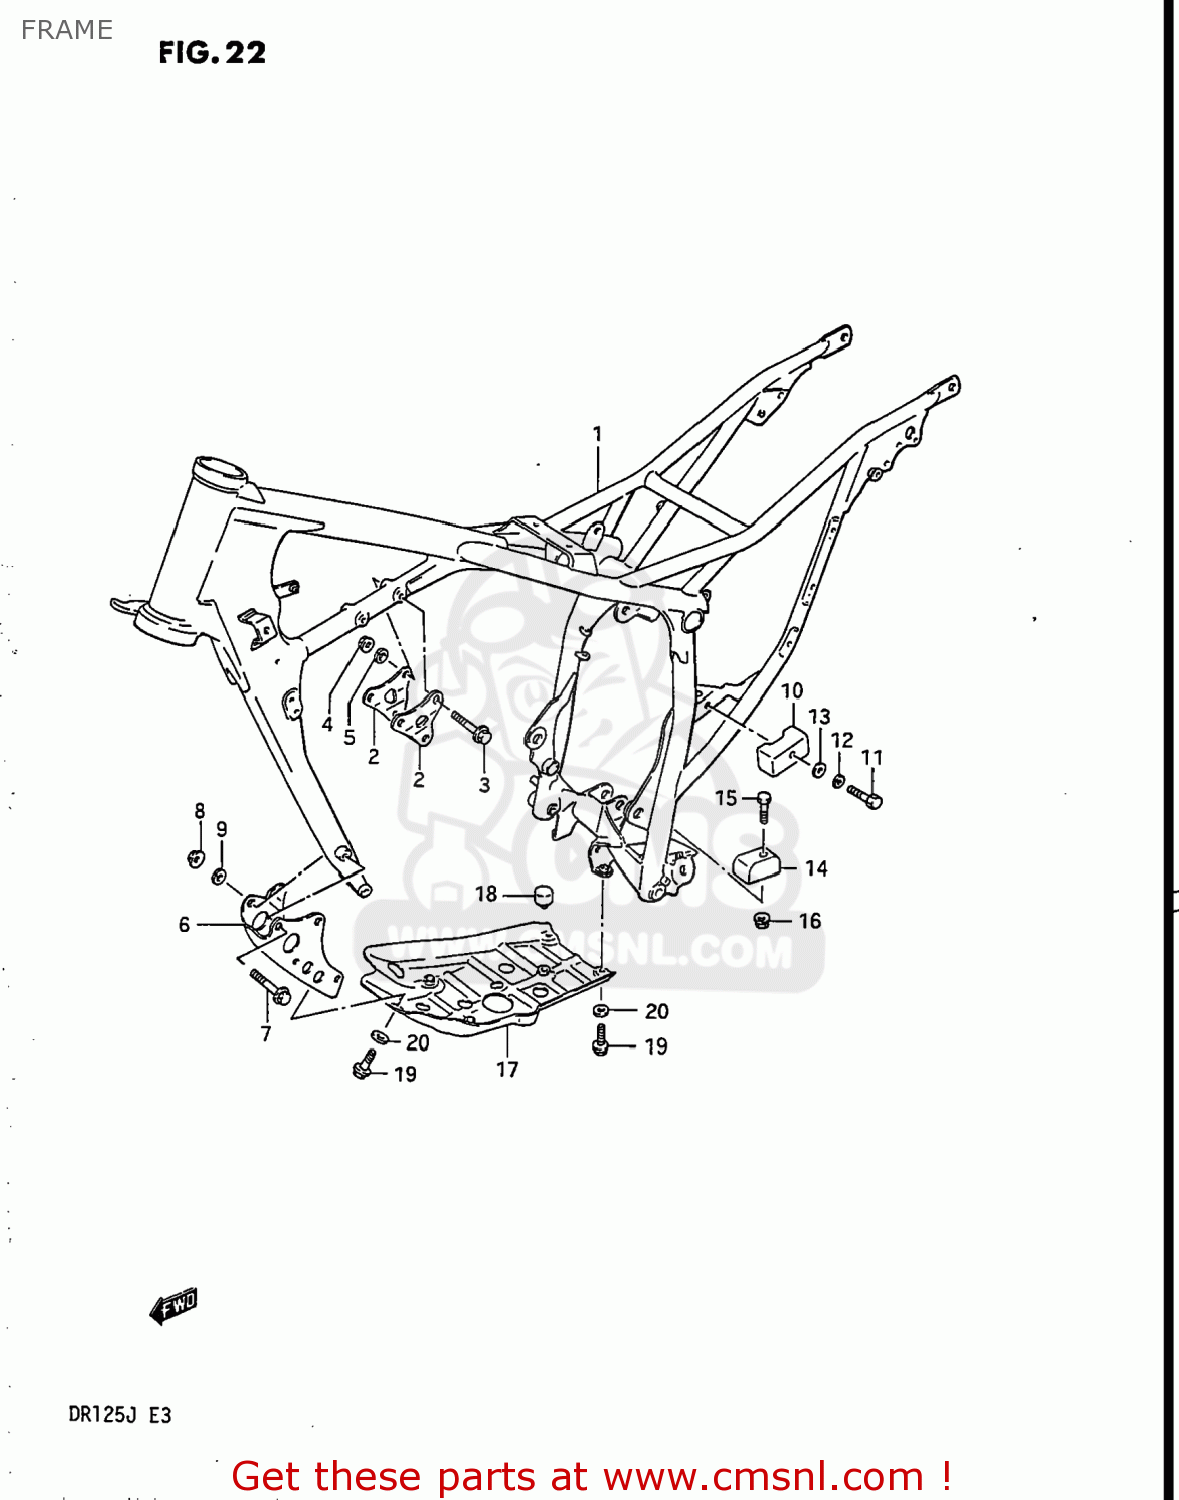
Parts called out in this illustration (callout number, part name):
1	FRAME
2	PLATE,ENGINE MOUNT UPR
3	BOLT
4	NUT
5	LOCK WASHER
6	PLATE,ENGINE MOUNTING
7	BOLT
8	NUT
9	LOCK WASHER
10	GUIDE,CH CONTROL UPR
11	BOLT 6X35
12	WASHER,LOCK
13	WASHER
14	GUIDE,CH LENGTH CONTROL LWR
15	BOLT
16	NUT 6MM
17	PROTECTOR,ENGINE
18	CUSHION
19	BOLT
20	WASHER
